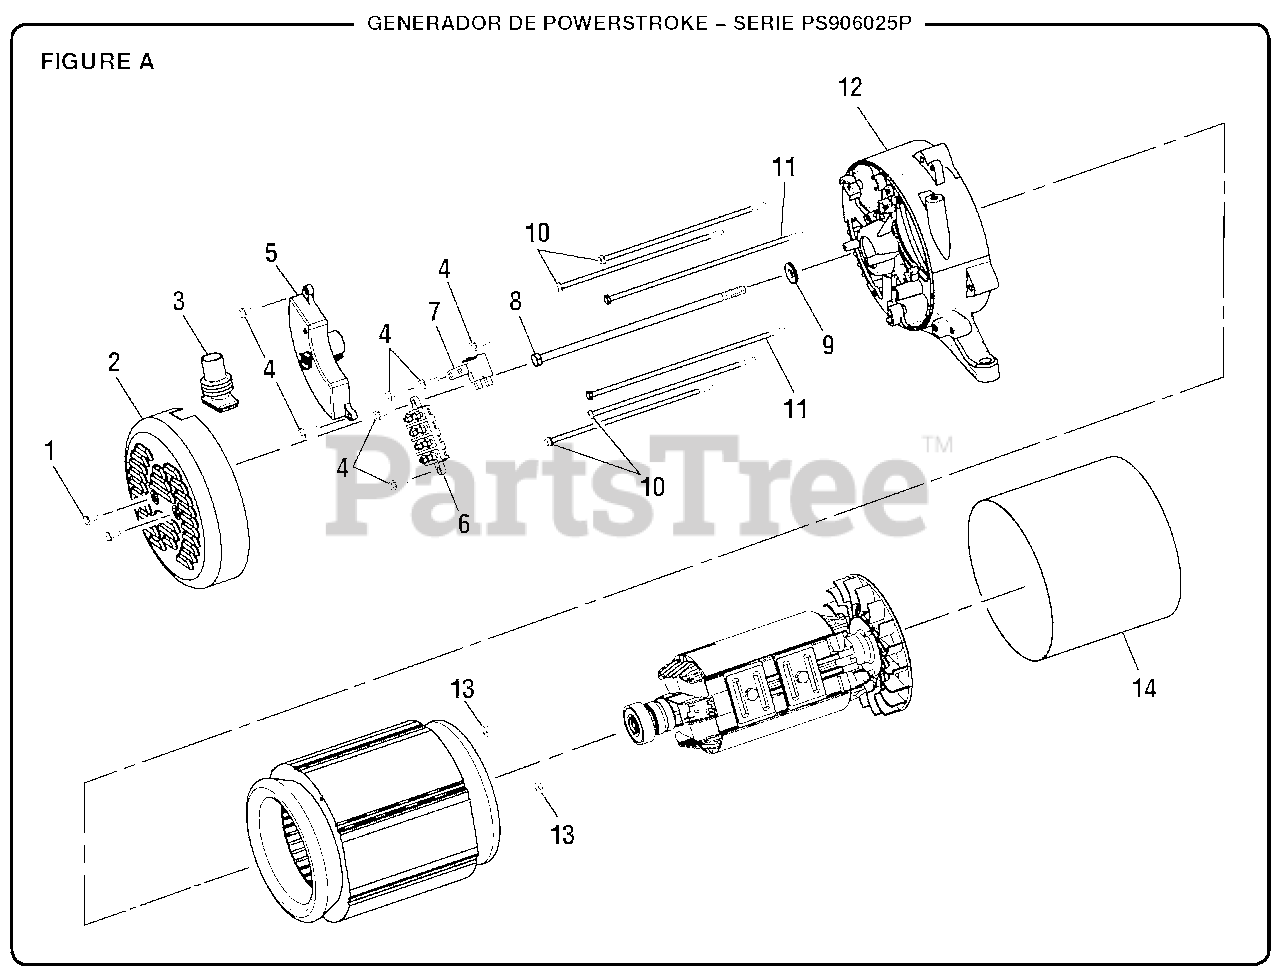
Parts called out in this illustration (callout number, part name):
1	Bolt (M5 x 10 mm, Hex Hd.)
2	Brush Cover
3	Rubber Boot
4	Bolt (M5 x 16 mm, Hex Hd.)
5	Automatic Voltage Regulator
6	Terminal Block
7	Brush Assembly Kit
8	Rotor Bolt (M12.7 x 242 mm, Hex Hd.)
9	Washer (5/16 in.)
10	Stator Bolt (1/4-20 x 7.5 in.)
11	Bolt (M5 x 230 mm, Hex Hd.)
12	Bearing Housing
13	Hex Nut (M5)
14	Generator Head Cover
